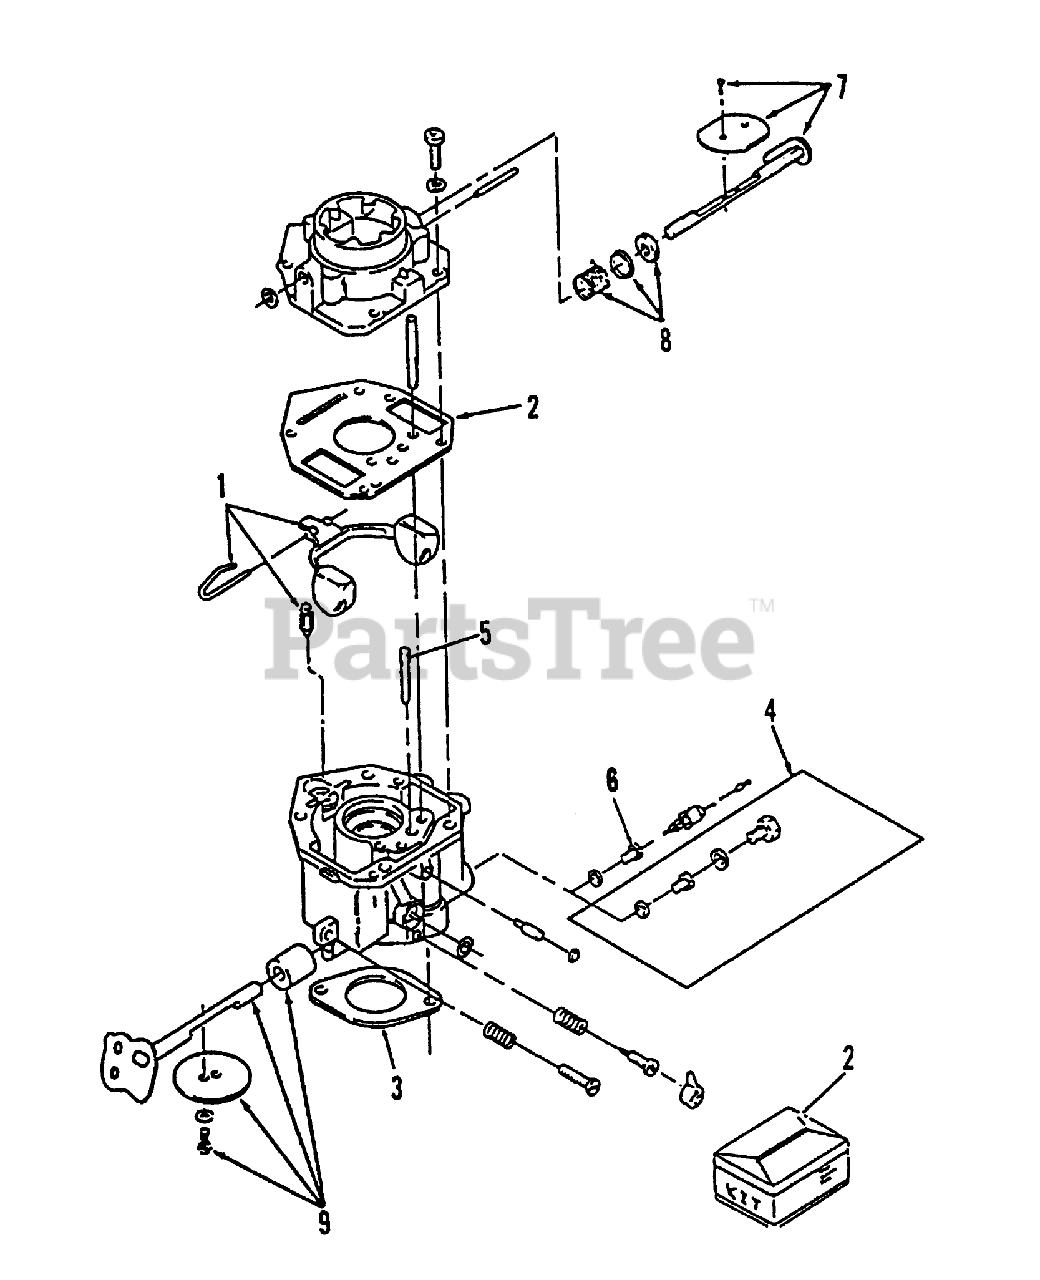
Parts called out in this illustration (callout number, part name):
2	REPAIR KIT
3	GASKET-CARBURETOR
8	CHOKE-LEVER KIT
